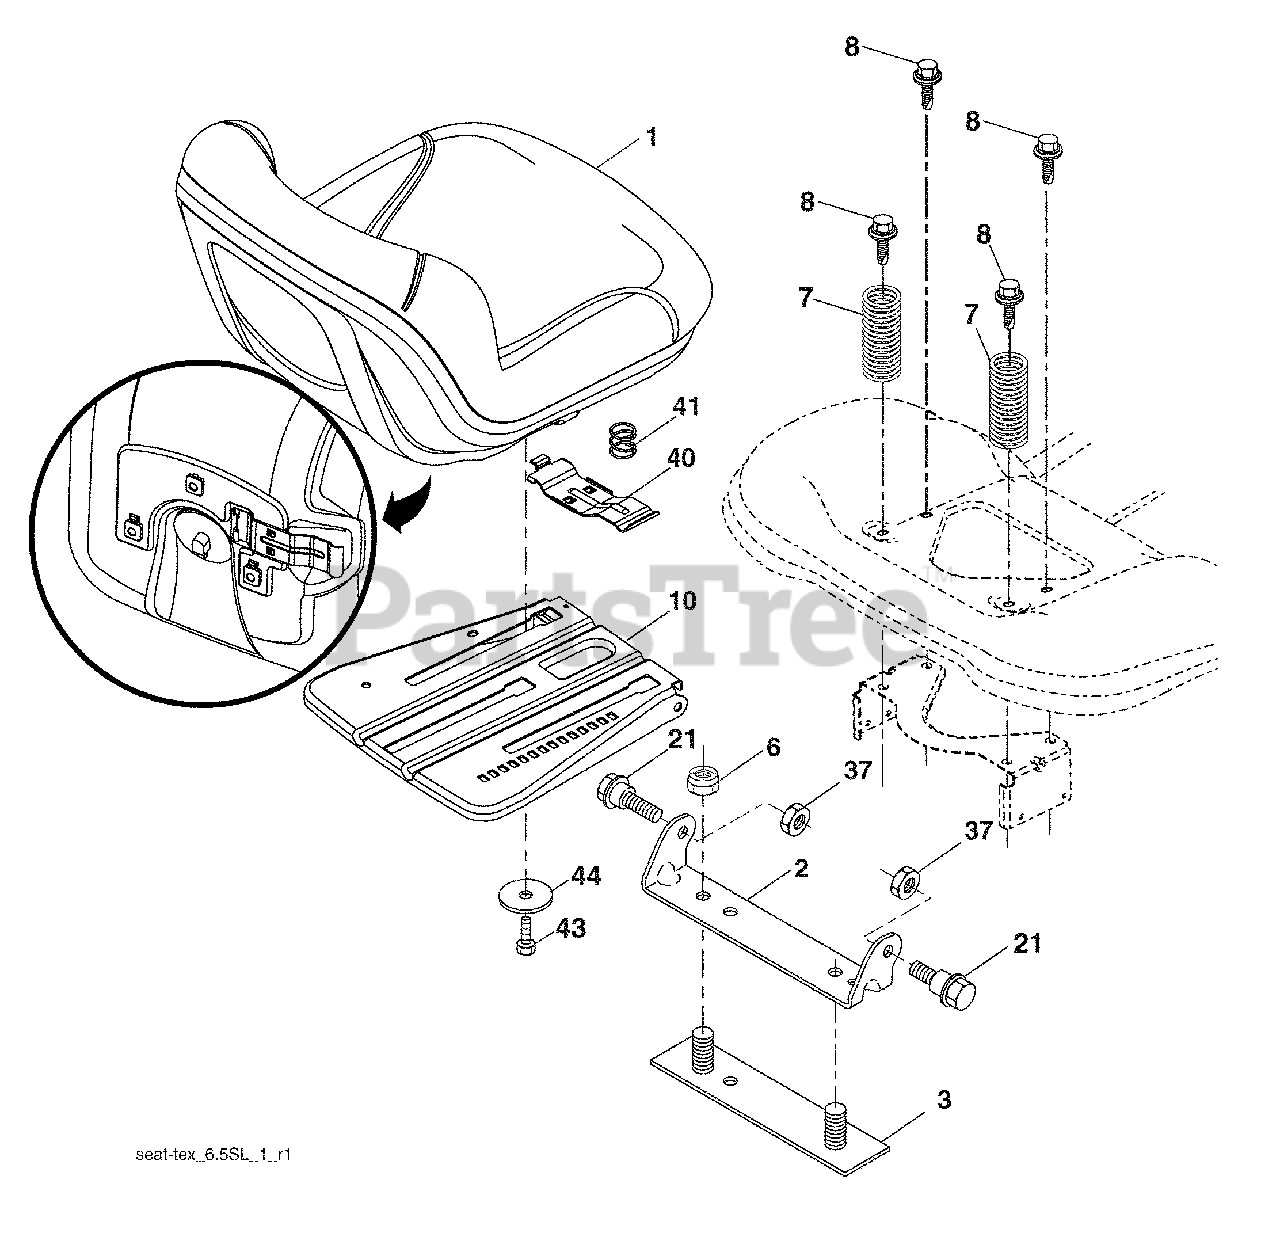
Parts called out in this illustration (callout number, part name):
1	Seat
2	Bracket Pivot Fender
3	Strap, Asm Fender
6	Nut, Lock w/Ins. 3/8-16 unc
7	Spring, Seat Cprsn
8	Bolt 5/16-18 unc x 3/4 w/Sems
10	Pan, Seat
21	Bolt, Shoulder 5/16-18
37	Nut, Lock 5/16-18 unc
40	Handle Slide Seat
41	Spring Latch Seat
43	Bolt Fin Hex 3/8-16 unc x 3/4
44	Washer 13/32 x 2-3/8 x 12 Ga.
